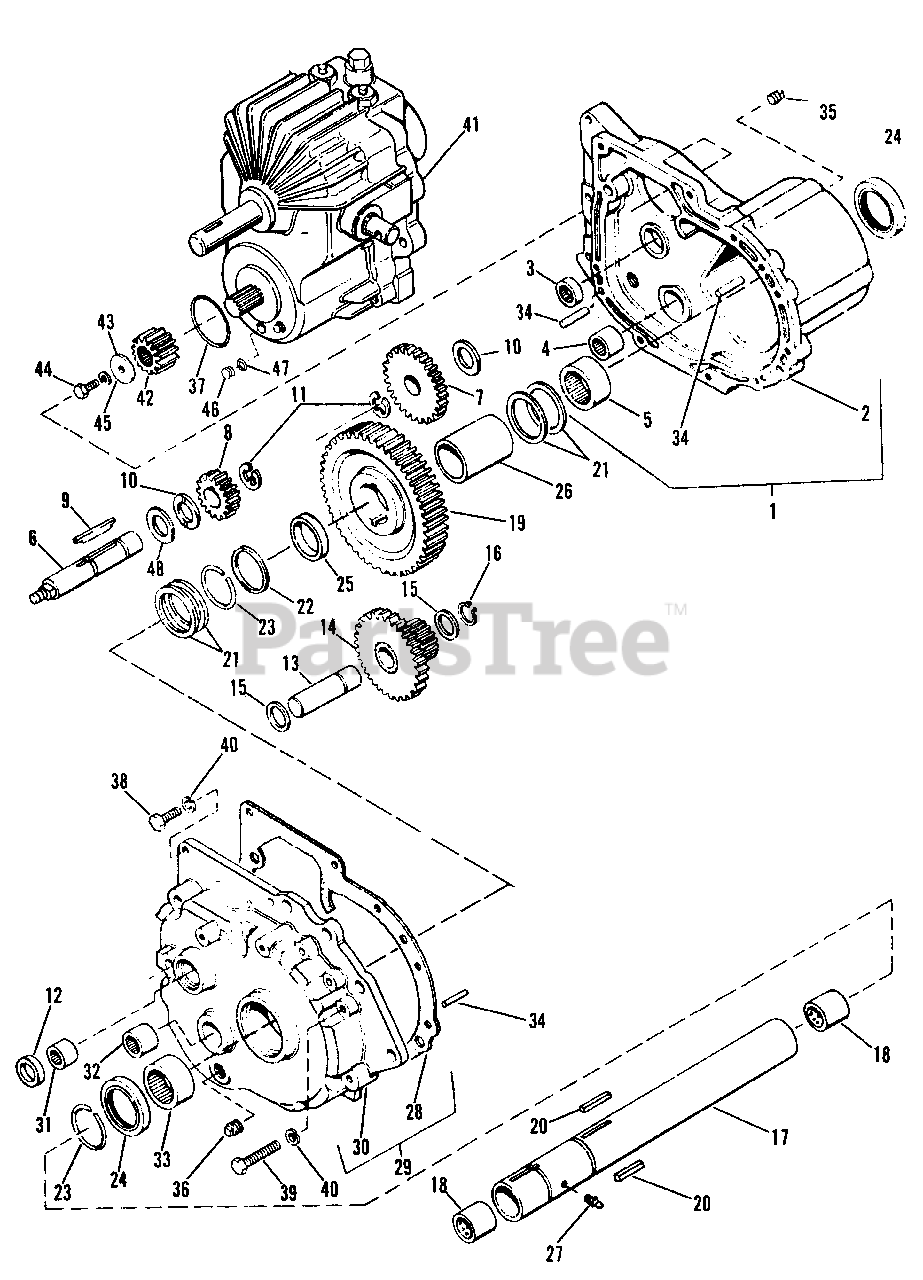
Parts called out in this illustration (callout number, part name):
1	GEAR CASE, Complete (Includes 2-5)
3	BEARING, Needle
4	BEARING, Needle
5	BEARING, Needle
6	SHAFT, Brake
7	GEAR, 1st, Interm.
8	PINION, 1st, Interm.
11	RETAINING, Ring
13	SHAFT, Interm.
14	PINION & SHAFT ASSEMBLY
16	RING, Retaining
17	AXLE TUBE ASSEMBLY
19	GEAR, Drive
25	SPACER, R.H. Axle
26	SPACER, L.H. Axle
27	FITTING, Grease
28	GASKET, Gear Case
29	COVER, Gear Case Complete (Includes 30-34)
30	COVER, Gear Case
31	BEARING, Needle
32	BEARING, Needle
33	BEARING, Needle
34	PIN, Roll
36	PLUG, Pipe
38	CAPSCREW, Hex, 5/16"-18 x 1" lg.
39	CAPSCREW, Hex, 5/16"-18 x 2" lg.
40	LOCKWASHER, 5/16"
41	HYDROSTATIC PUMP & MOTOR UNIT
42	PINION, Motor Shaft
44	CAPSCREW, Hex, 5/16"-18 x 3/4" lg.
45	LOCKWASHER, 5/16"
